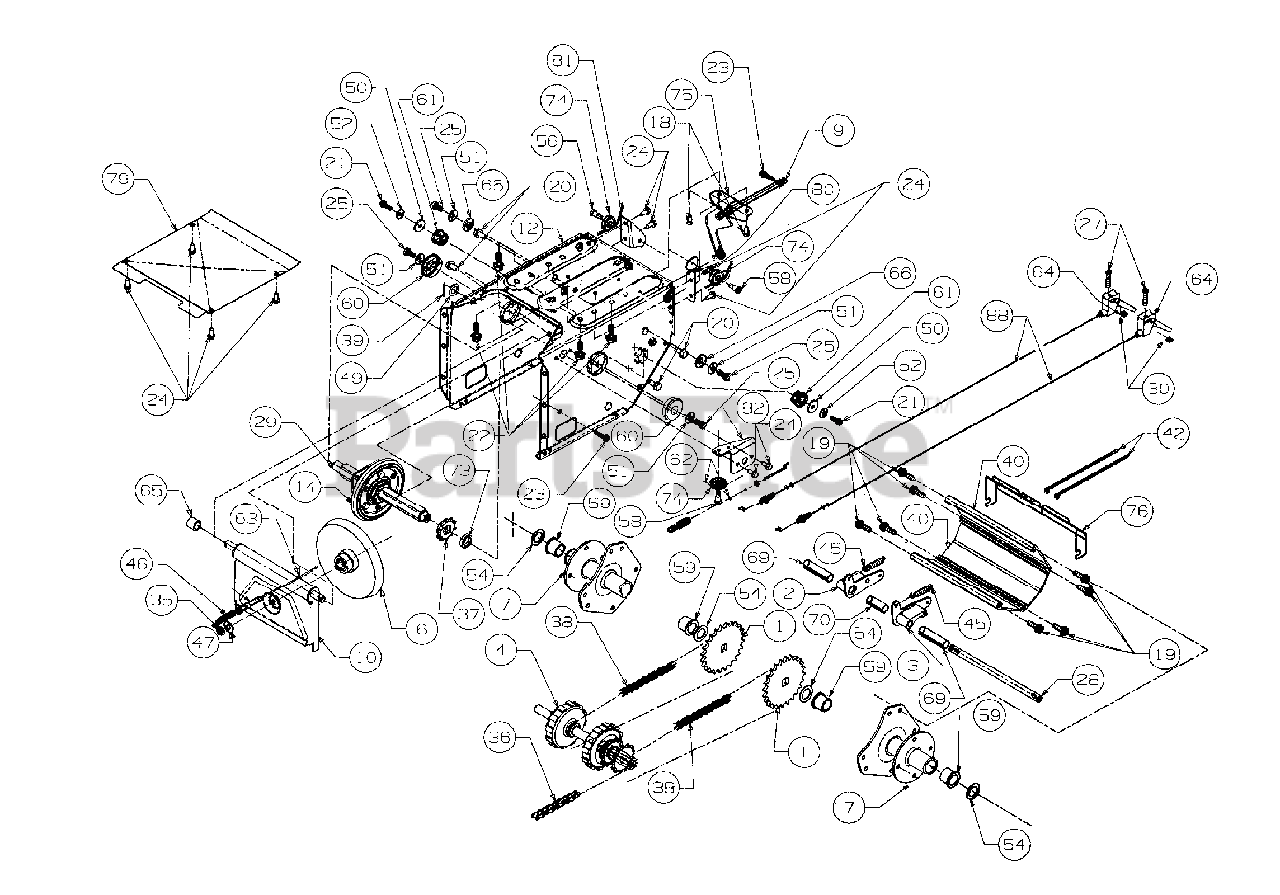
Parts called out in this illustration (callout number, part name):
1	Axle Assembly
2	Dog Assembly - R.H.
3	Dog Assembly - L.H.
4	Shaft Assembly
6	Disc Assembly
14	Wheel Assembly Friction
18	Screw
19	Screw
20	Screw
21	Screw
23	Screw
24	Screw
25	Screw
27	Screw
28	Shaft
29	Shaft
30	Nut Flange
35	Nut Jam
36	Chain
37	Sprocket
38	Chain
39	Pin Cotter
40	Housing Track
42	Cable Tie
45	Spring
46	Spring
47	Washer - Bell
49	Washer - Flat
50	Washer - Flat
51	Washer - Bell
52	Washer - Bell
54	Washer - Flat
56	Lubricant
58	Screw - Shoulder
59	Bearing - Flange
60	Bearing - Ball
61	Bearing - Hex Flange
62	Cable - Auger Clutch
63	Cable - Drive Clutch
64	Cable with Trigger Lever
65	Spacer
66	Spacer - Shoulder
69	Spacer - Split
70	Spacer - Split
73	Spacer
74	Roller - Cable
